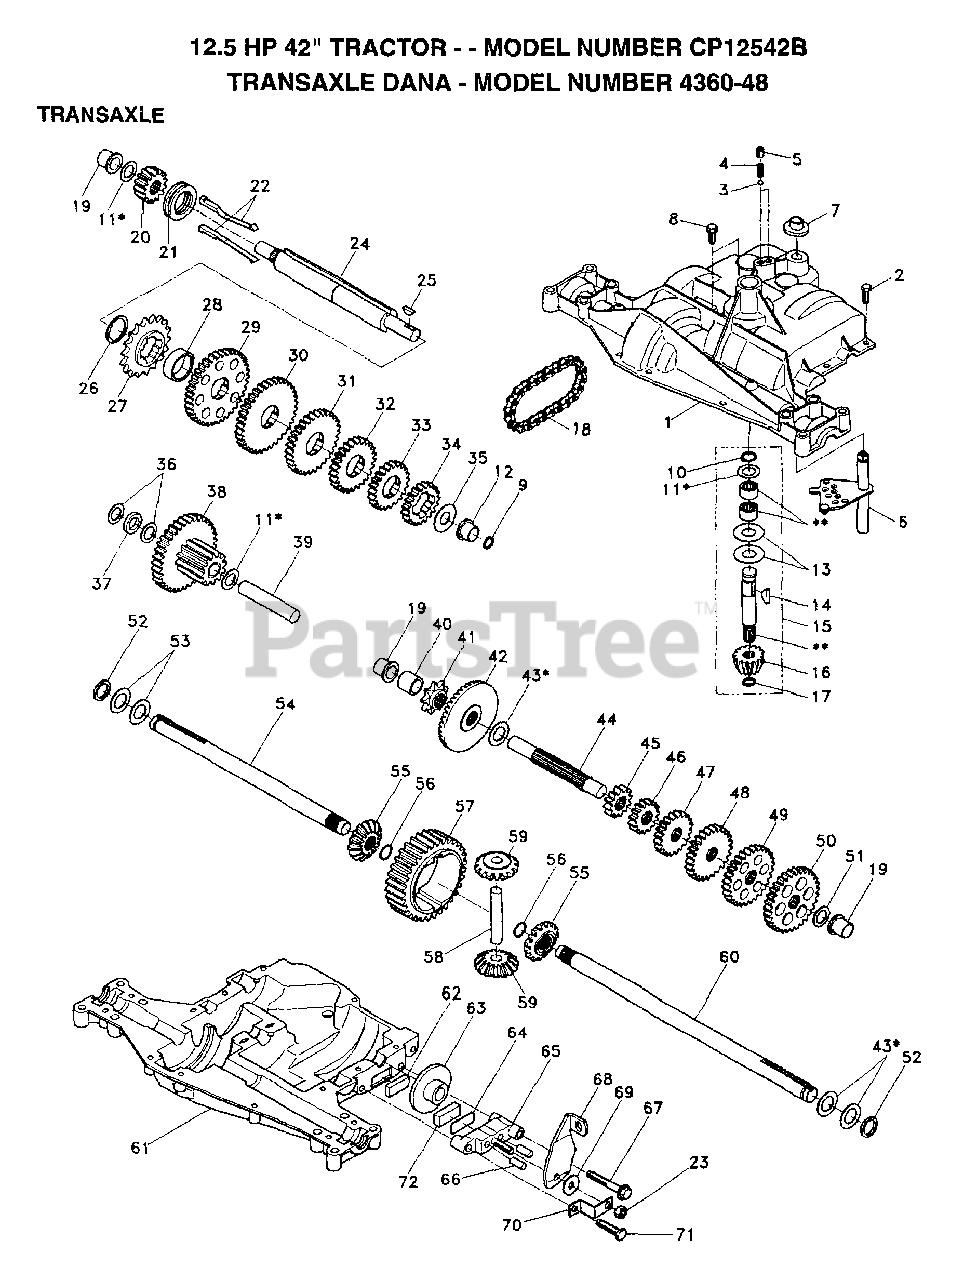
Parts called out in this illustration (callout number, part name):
1	HOUSING UPPER
3	BALL, DETENT
4	SPRING, DETENT
5	SCREW, SET
6	SHIFTER ASSEMBLY
7	BOOT, SHIFTER
8	SCREW TAPPING WITH SEALER
9	SQUARE RING
10	RING RETAINING
11	ASSY, KIT, SHIM .625 SHAFT
12	BEARING FL
13	WASHER, PLAIN .632 X 1.38 X .046
14	KEY WOODRUFF #9
15	ASSEMBLY, KIT, INPUT SHAFT
16	PINION, BEVEL, 14 TEETH
17	RING, RETAINING
18	CHAIN, 24 PITCHES
19	BEARING, FLANGE
21	COLLAR, CLUTCH
22	ASSEMBLY, KIT, CLUTCH KEYS
23	LOCKNUT 5/16-24
24	SHAFT INTERMEDIATE
25	KEY, WOODRUFF, #61
26	RING, RETAINING
27	SPROCKET, 18 TEETH
29	GEAR, SPUR, 37 TEETH
30	GEAR, SPUR, 35 TEETH
31	GEAR, SPUR, 30 TEETH
32	GEAR, SPUR, 25 TEETH
33	GEAR, SPUR, 22 TEETH
34	GEAR, SPUR, 19 TEETH
35	WASHER, PLAIN .640 X 1.37 X .061
36	WASHER, PLAIN .632 X 1.00 X .026
37	SPACER .630 X 1.00 X .169
38	ASSY GEAR COMB 12&35 TEETH
39	SHAFT, IDLER
40	SPACER .635 X .875 X .755
41	SPROCKET, 9 TEETH
42	GEAR, BEVEL, 42 TEETH
43	ASSY, KIT, SHIM .750 SHAFT
44	SHAFT, DRIVE
45	GEAR, SPUR, 12 TEETH
46	GEAR SPUR, 15 TEETH
47	GEAR, SPUR, 20 TEETH
48	GEAR, SPUR, 25 TEETH
49	GEAR, SPUR, 28 TEETH
50	GEAR, SPUR, 31 TEETH
51	WASHER, PLAIN .632 X 1.00 X .060
52	WASHER, NEOPRENE
53	WASHER, PLAIN, 1.00 X .505 X .020
54	AXLE LEFT HAND
55	GEAR, MITER, 15 TEETH
56	RING, RETAINING
57	GEAR, SPUR, 32 TEETH
58	SHAFT, CROSS
59	GEAR, MITER, 15 TEETH
60	AXLE, R.H.
61	HOUSING LOWER
62	PUCK, FRICTION
63	DISC, BRAKE
65	JAW, BRAKE
66	PIN, DOWEL
67	SCREW, SELF-TAPPING
68	LEVER ACTUATING
69	WASHER, PLAIN .321 X 1.00 X .055
70	BRACKET, ANTI-ROTATION
71	SCREW TAPPING
72	PUCK, FRICTION
